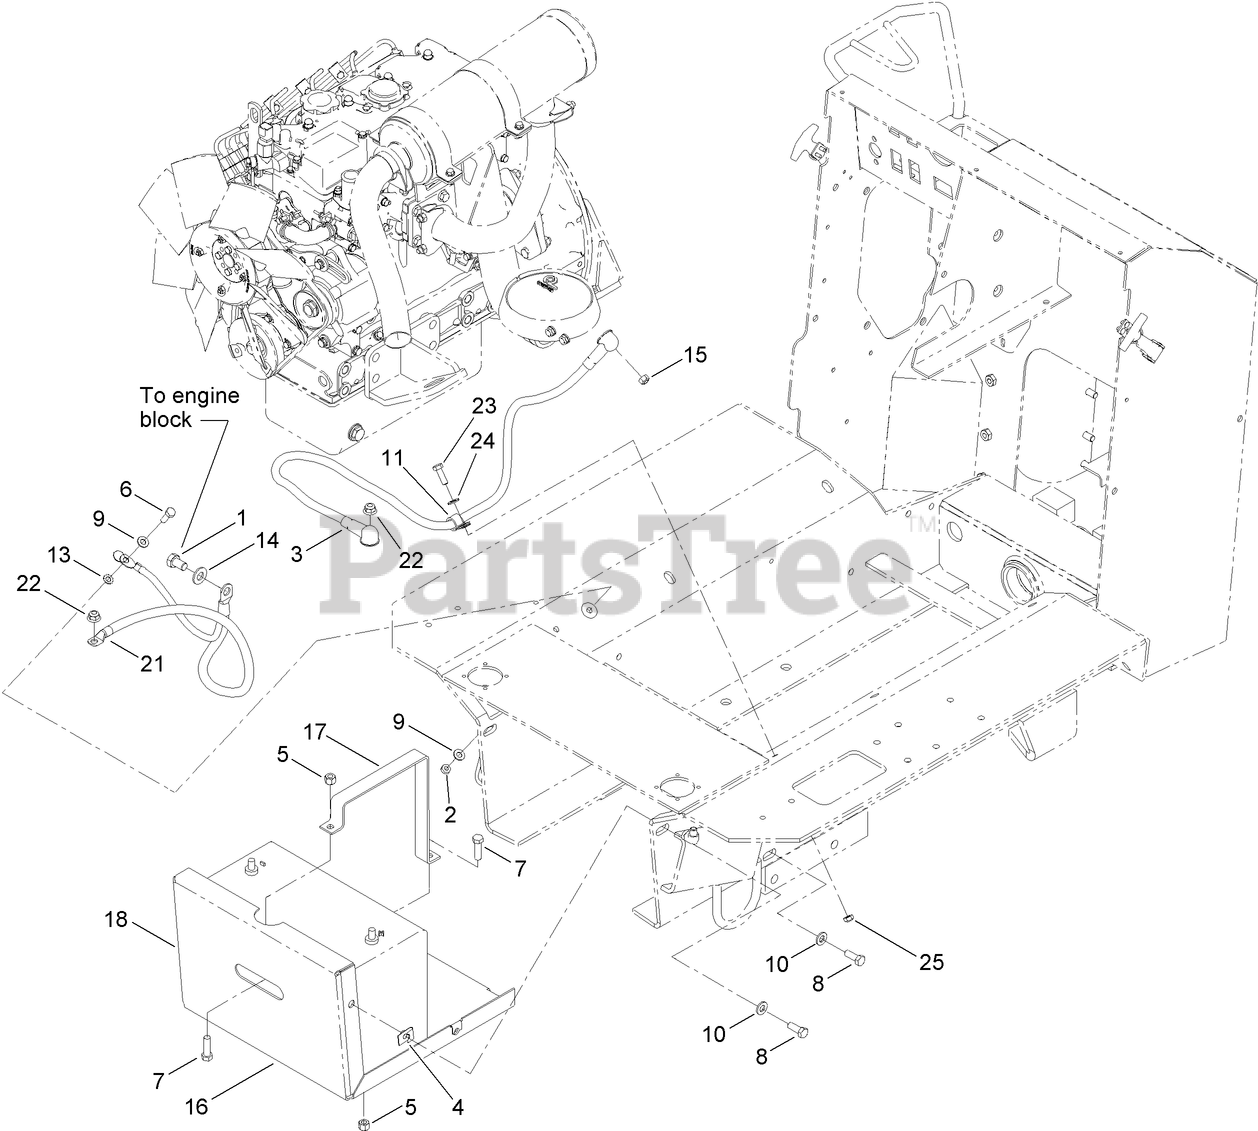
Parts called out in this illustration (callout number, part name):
1	SCREW-HH
2	NUT-HEX
3	CABLE-BATTERY, POSITIVE
4	NUT-SPRING
5	NUT-HEX
6	SCREW-HH
7	SCREW-HH
8	SCREW-HH
9	WASHER-FLAT
10	WASHER-FLAT
11	CLAMP-CABLE
13	WASHER-LOCK
14	WASHER-FLAT
15	NUT-LOCK, NI
17	BRACKET-BATTERY
18	RACK-BATTERY
21	CABLE-BATTERY, NEGATIVE
22	NUT-HF, NI
23	SCREW-HH
24	WASHER-FLAT
25	NUT-LOCK, CONE
